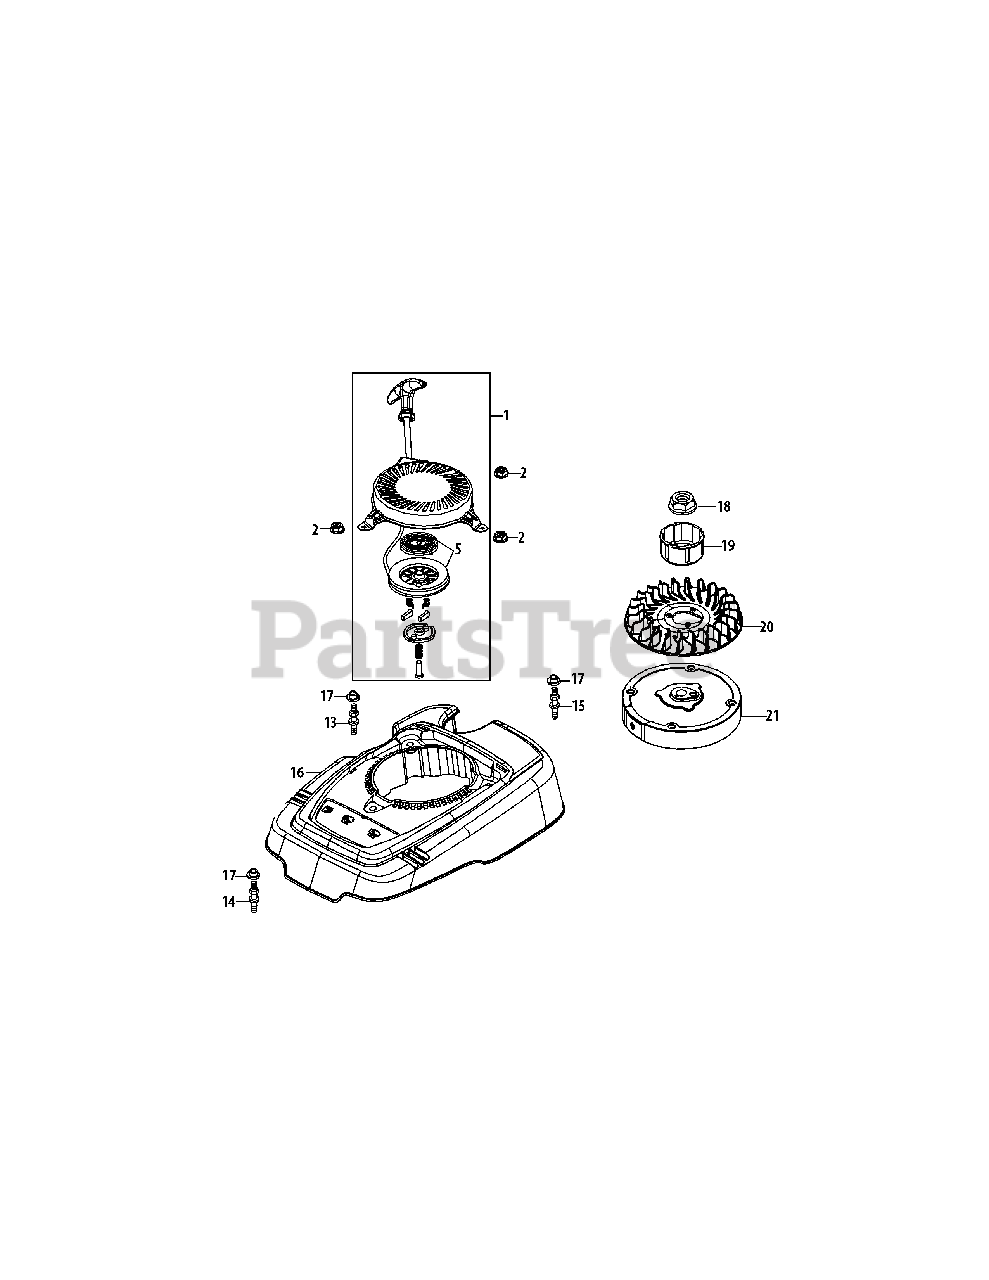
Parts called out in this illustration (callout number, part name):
1	Recoil Starter Assembly
2	Nut M6X10Mm Starter/Carb/Muffler
5	Recoil Spring and Pulley Ass'y
13	Starter/Shroud Stud Left/Black
14	Starter/Shroud Stud Front/Unmarked
15	Starter/Shroud Stud Right/White
16	M6 Integrated Shroud
17	Spacer
18	Flywheel Nut M14
19	Starter Cup
20	Cooling Fan
21	Flywheel
